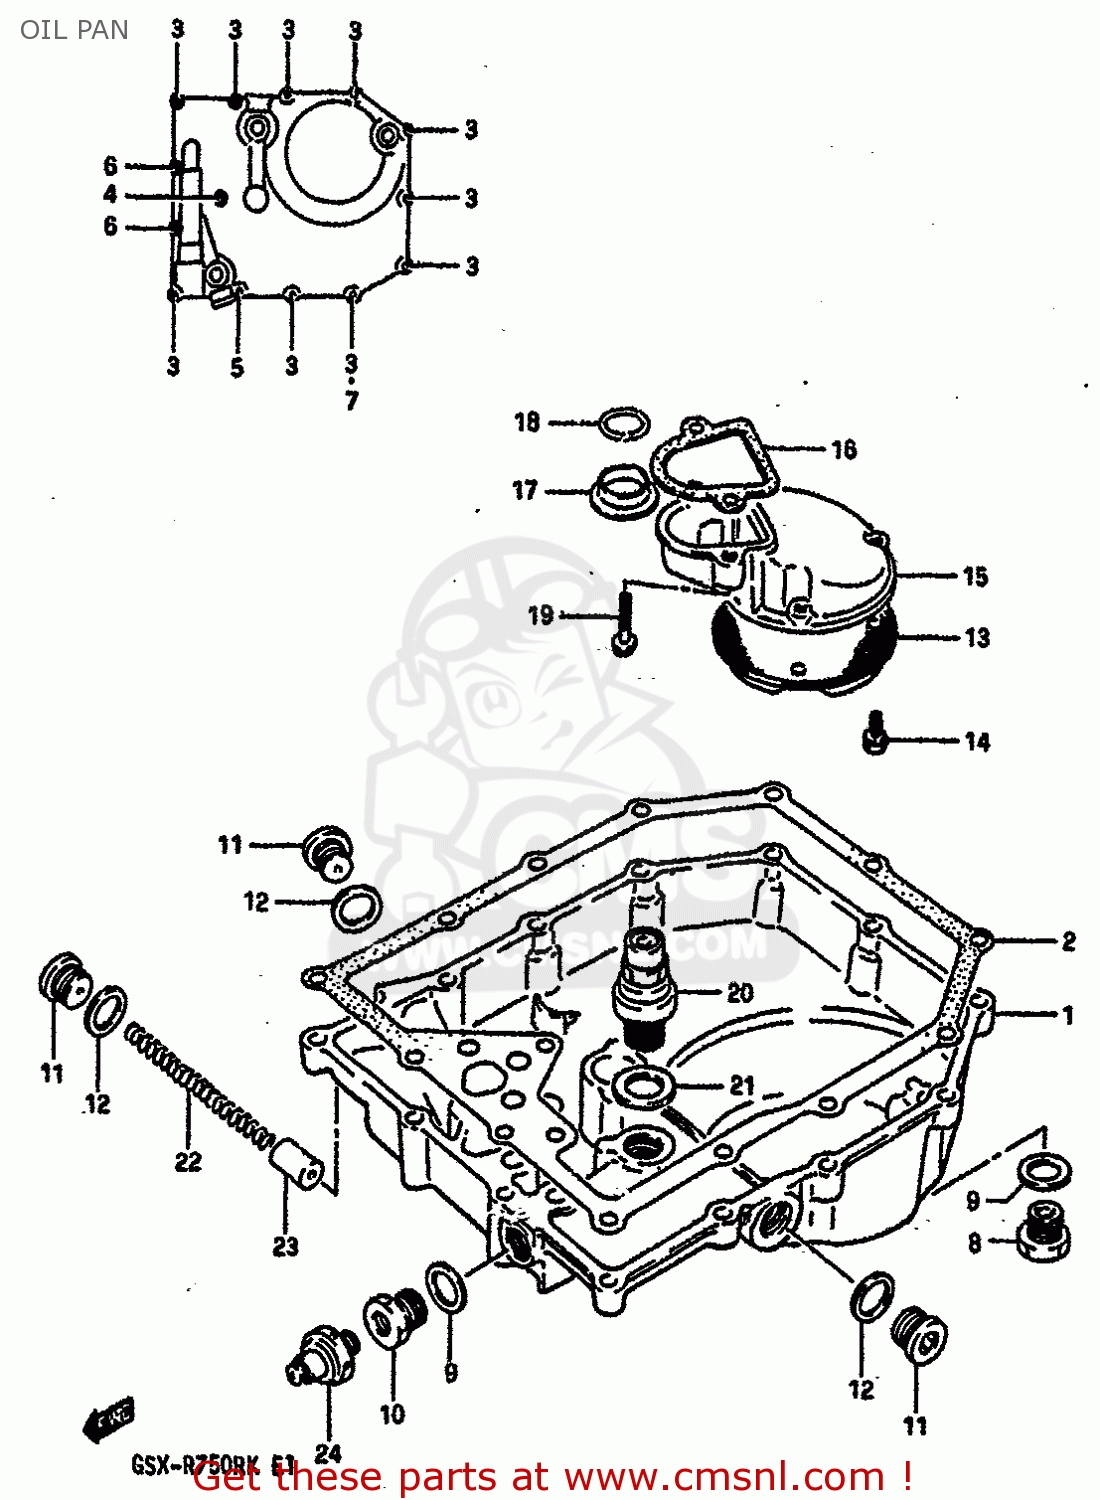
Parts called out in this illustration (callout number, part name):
1	PAN,OIL
2	GASKET,OIL PAN (NAS)
3	BOLT
4	BOLT
5	BOLT
6	BOLT
7	GASKET(5.8X11X1.2) (NAS)
8	PLUG
9	GASKET(14X19.2X2) (NAS)
10	PLUG,PRESSURE SW
11	PLUG
12	GASKET(16X22X2) (NAS)
13	STRAINER,ENGINE OIL
14	BOLT
15	PROTECTOR,OIL STRAINER
16	GASKET,OIL STRAINER PROTECTOR (NAS)
17	GASKET,OIL OUTLET (NAS)
18	O RING(D:3.2,ID:17.8)
19	BOLT
20	VALVE ASSEMBLY,OIL RELIEF
21	GASKET(16X22X2) (NAS)
22	SPRING
23	PLUNGER,OIL CONTROLL
24	SWITCH ASSEMBLY
